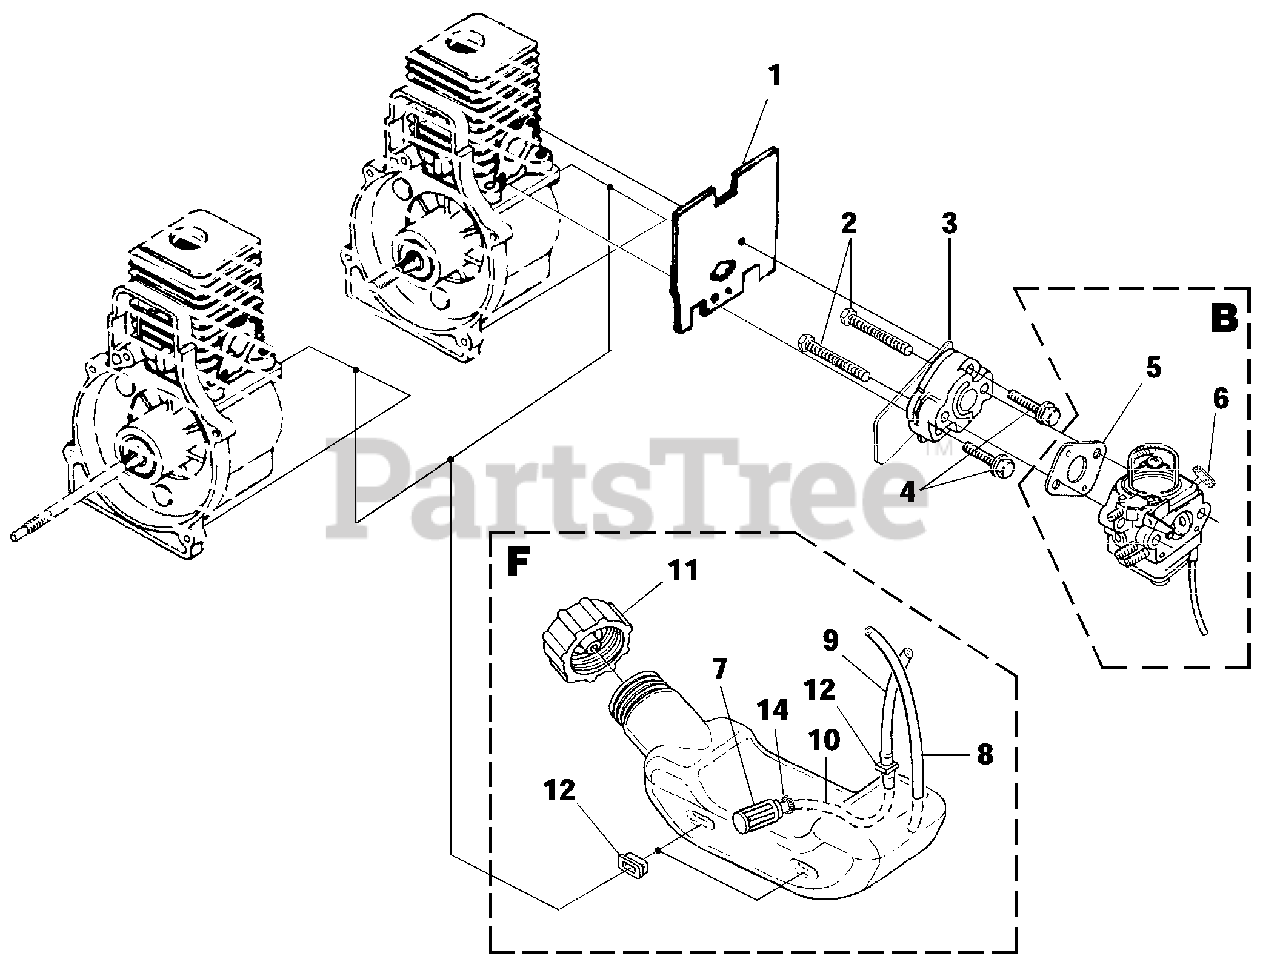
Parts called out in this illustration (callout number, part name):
1	GASKET-Heat Dam
2	SCREW-Machine (10-24 X 2 1/4")
3	HEAT DAM
4	SCREW-Sems (10-24 X 1")
5	GASKET-Carburetor
6	Lever-Choke (Zama)
7	FILTER-Fuel
8	TUBING-Rubber
9	TUBING-Rubber
10	TUBING-Rubber
11	FUEL CAP
12	BUMPER-Rubber
14	CLAMP
B	CARBURETOR KIT (Non-Clutch)
F	FUEL TANK ASSY.
